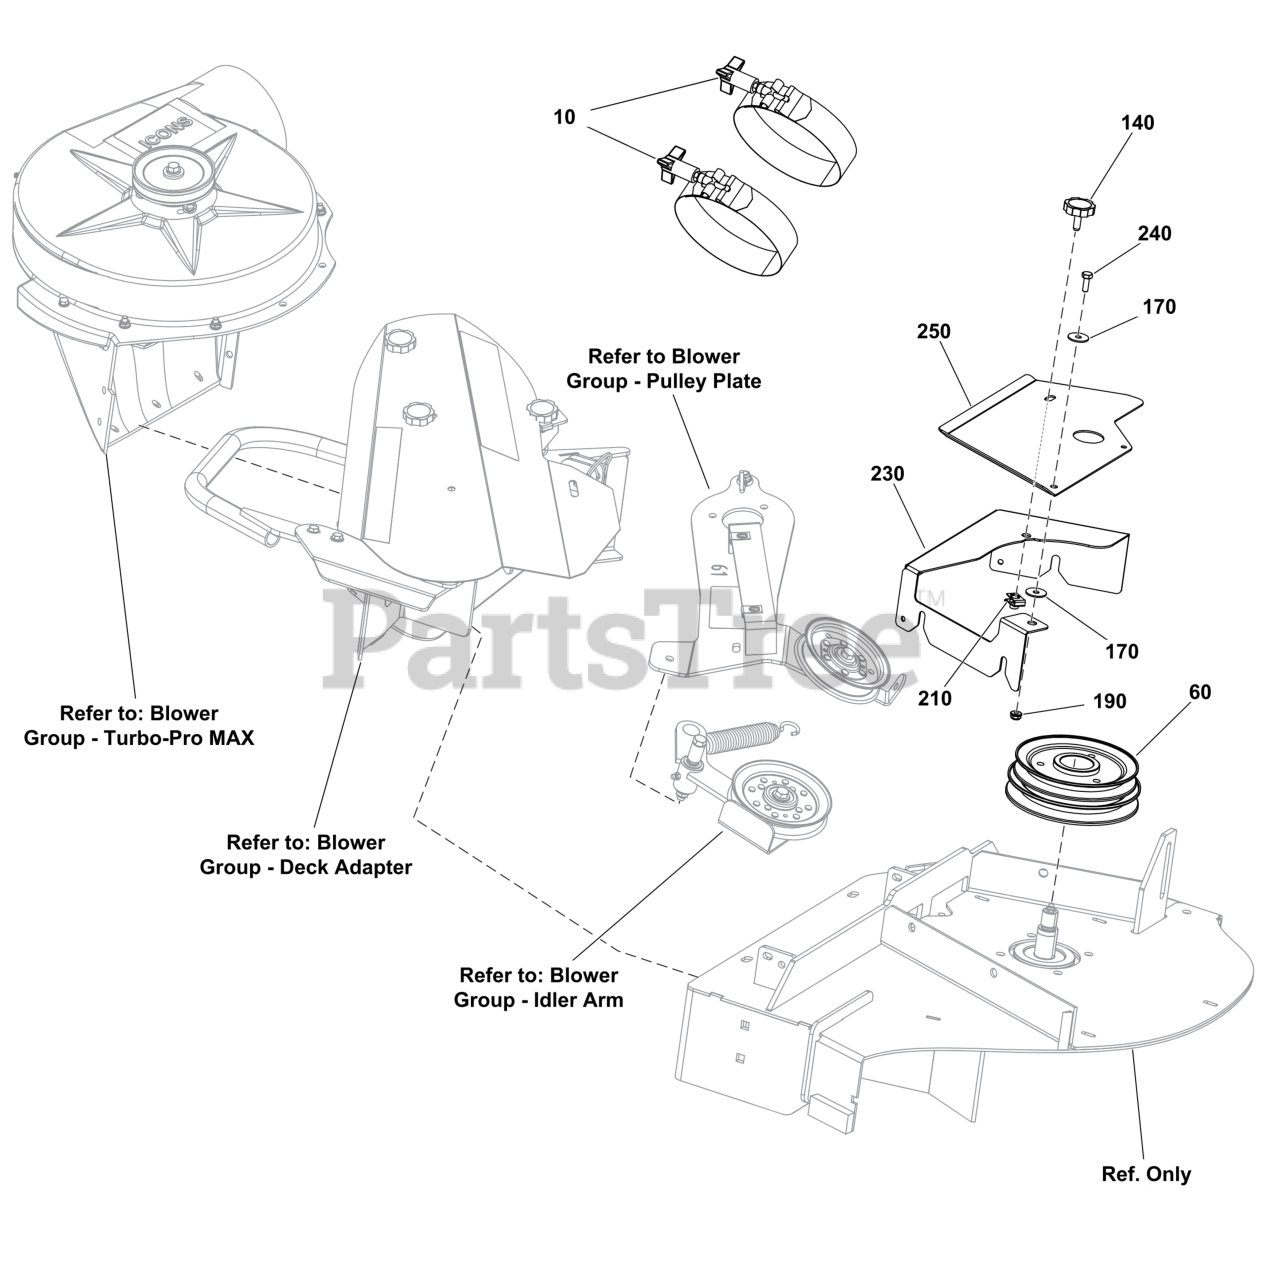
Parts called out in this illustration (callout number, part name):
60	PULLEY, Double
140	KNOB, 5/616-18 X 1
170	WASHER, 1/4 FENDER
210	NUT, SPEED, 5/16-18 L
230	GUARD, Pulley
240	BOLT, 1/4-20 X 3/4" G
250	SHIELD, Belt
